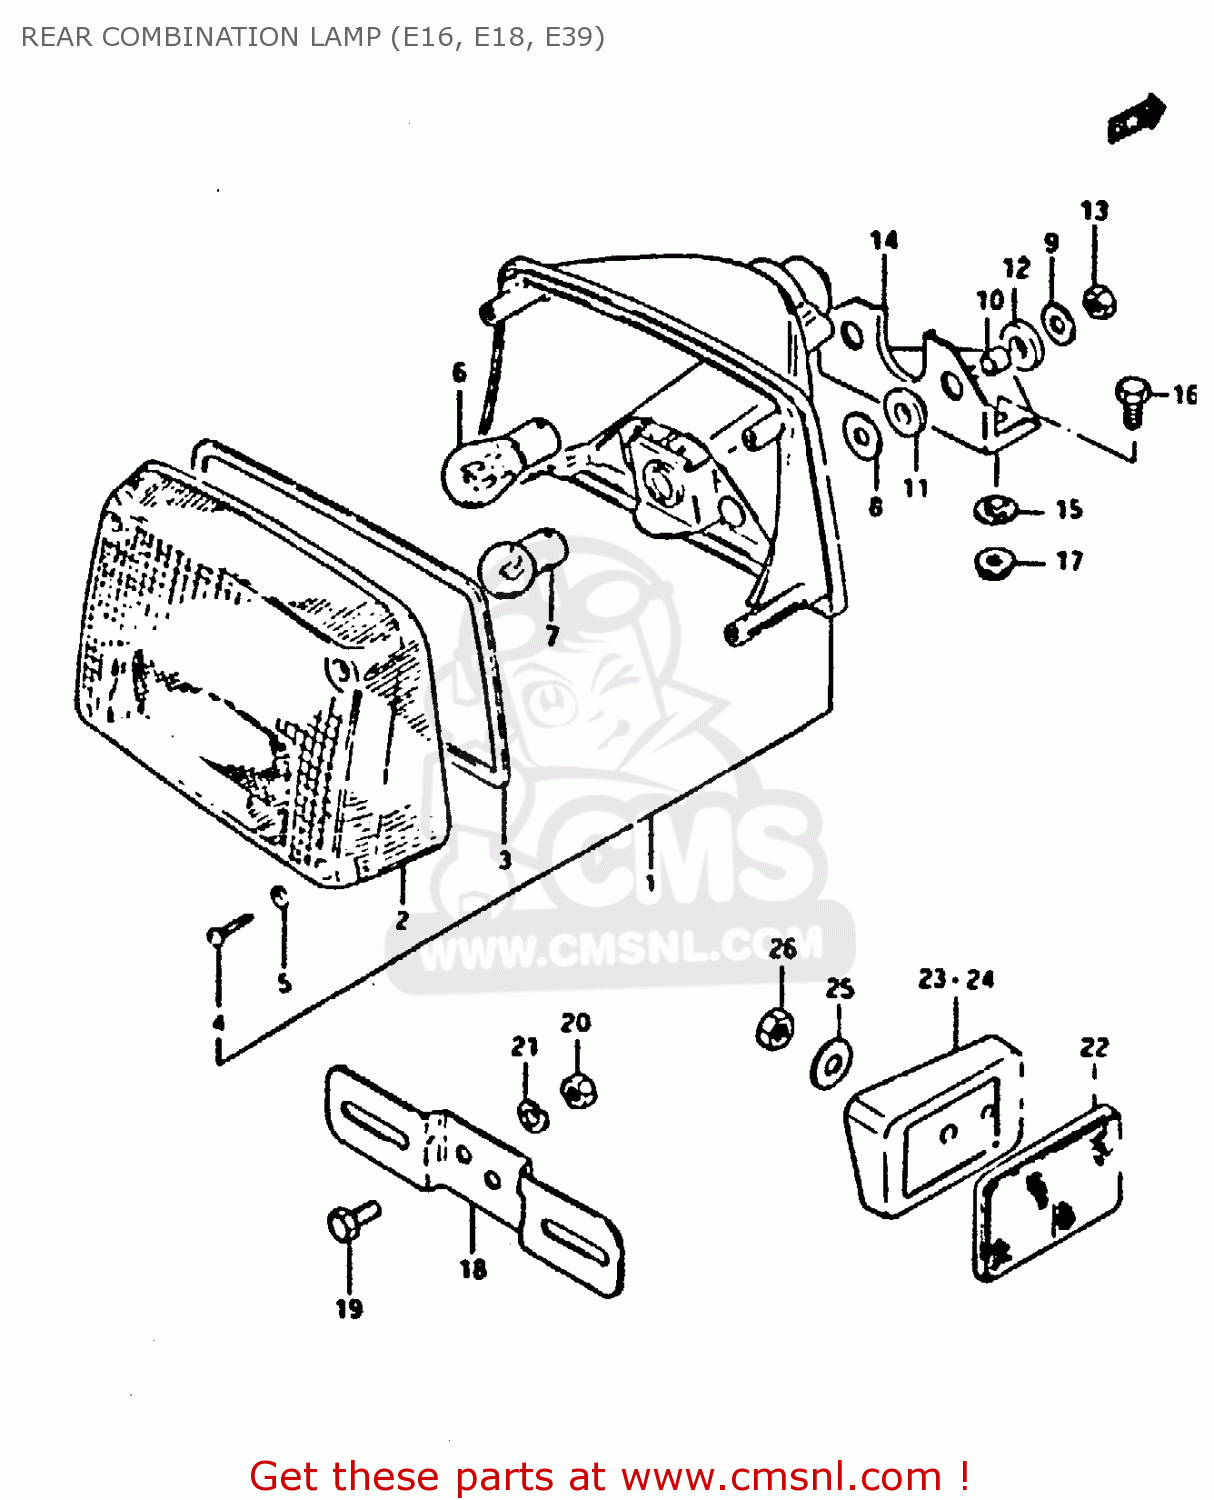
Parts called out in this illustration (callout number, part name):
1	LAMP ASSY, REAR COMBINATION
2	LENS,RR COMBI
3	GASKET (NAS)
4	SCREW,REAR COMBINATION LAMP
5	GASKET (NAS)
6	BULB 12V21/5W
7	BULB
8	WASHER
9	WASHER(6,5X22X1.6)
10	SPACER(6.1X9X7.5)
11	CUSHION
12	CUSHION
13	NUT 6MM
14	BRACKET,RR COMBINATION LAMP
15	WASHER
16	BOLT, UPPER
17	NUT 6MM
18	BRACKET, LICENSE PLATE
19	BOLT,REAR
20	NUT
21	LOCK WASHER
22	REFLECTOR,REFLEX
23	SPACER
24	SPACER
25	WASHER(5.2X16X1)
26	NUT
